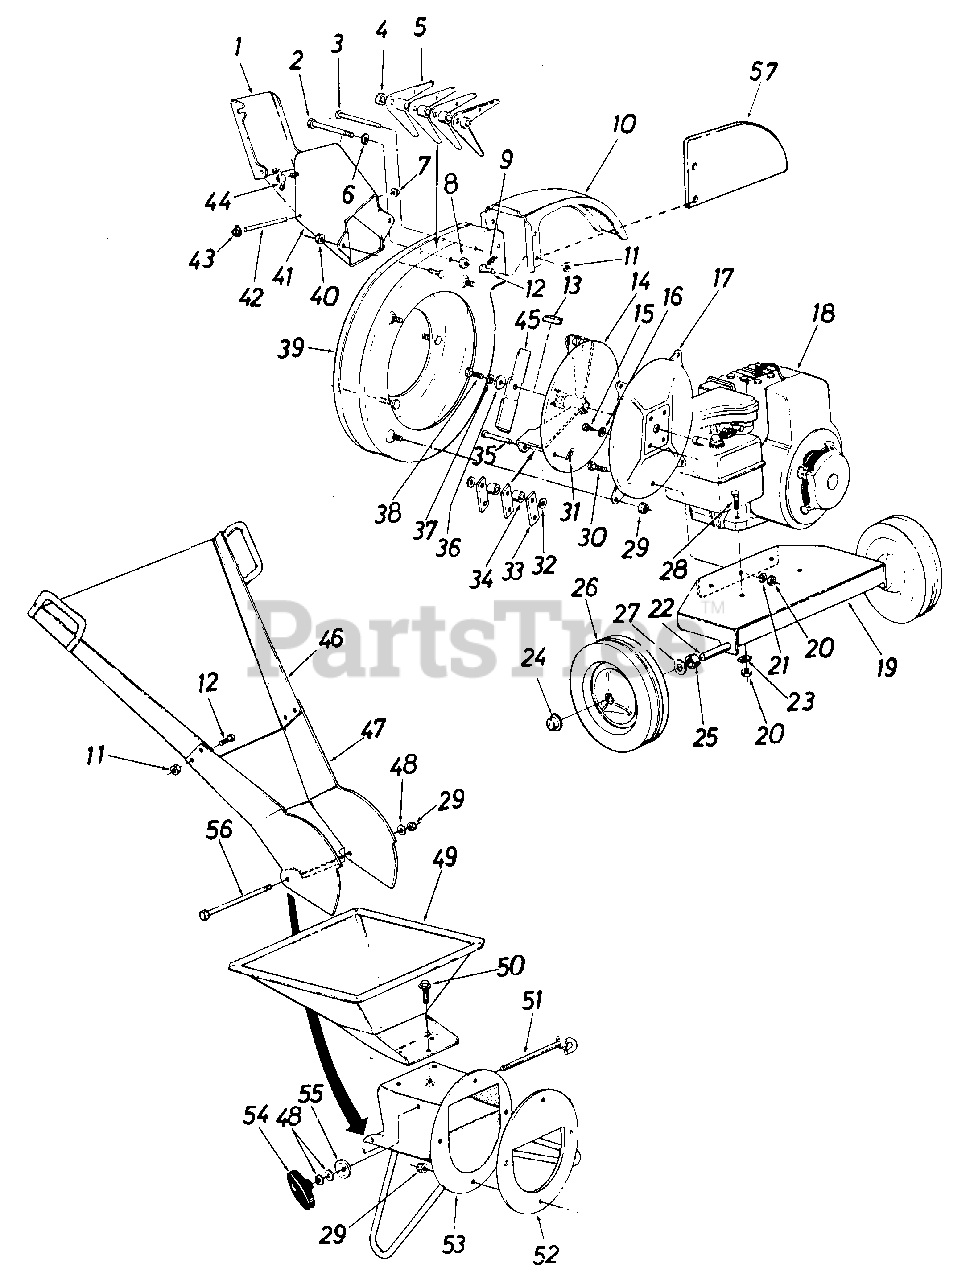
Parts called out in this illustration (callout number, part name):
2	SCREW-HEX 1/2-20 X 4.50
3	PIN-CLEVIS-5/16 X3 5/8
5	CUTTING FINGER
6	WASHER-LOCK-1/2
8	NUT-HEX JAM 1/2-20
9	PIN-COTTER-3/32 DIA X .75
10	DEFLECTOR-CHUTE
11	NUT-HEX CENTER L-1/4-20
12	SCREW-HEX 1/4-20 X .50
13	KEY-SQ 1/4 X 2.00
14	IMPELLER ASSY-COMP
15	SCREW-HEX 5/16-24 X .75
16	WASHER-LOCK-5/16
17	PLATE-MTG
19	PLATE-ENGINE MTG
20	NUT-5/16-24
21	WASHER-LOCK-5/16
23	WASHER-SPEC L 5/16 X .88 OD
26	WHEEL ASSY W/TIRE-8 X 1.75 TL
27	WASHER-FL-.531 ID X 1.25 OD X .036
28	SCREW-5/16-24 X 1.5
29	NUT-HEX INS L-5/16-18
30	SCREW-HEX 5/16-24 X .62
31	PIN-COTTER-1/8 DIA X 1
32	WASHER-FL-.531 ID X .93 OD X .090
33	FLAIL
34	SPACER-FLAIL
35	PIN-CLEVIS-1/2 X 3
36	WASHER-FL-HOND .410ID X 1.255X.162
37	WASHER-HDL 3/8
38	SCREW-HEX 3/8-24 X 2.00
41	EXTENSION ASSY-GUARD
42	PIN-HINGE
44	NUT-INS WING L-1/4-20
47	EXTENSION-GUARD
48	WASHER-FL-.344 X .62
49	HOPPER ASSY
50	SCREW-HEX WASH SF TAPP
51	ROD ASSY-CLAMP
52	PLATE-BACK-UP
53	GUARD ASSY-INLET
54	KNOB-HANDLE ASSY
55	WASHER-STOP
56	SCREW-HEX 5/16-18 X 8.25
57	PLATE-DEFLECTOR
